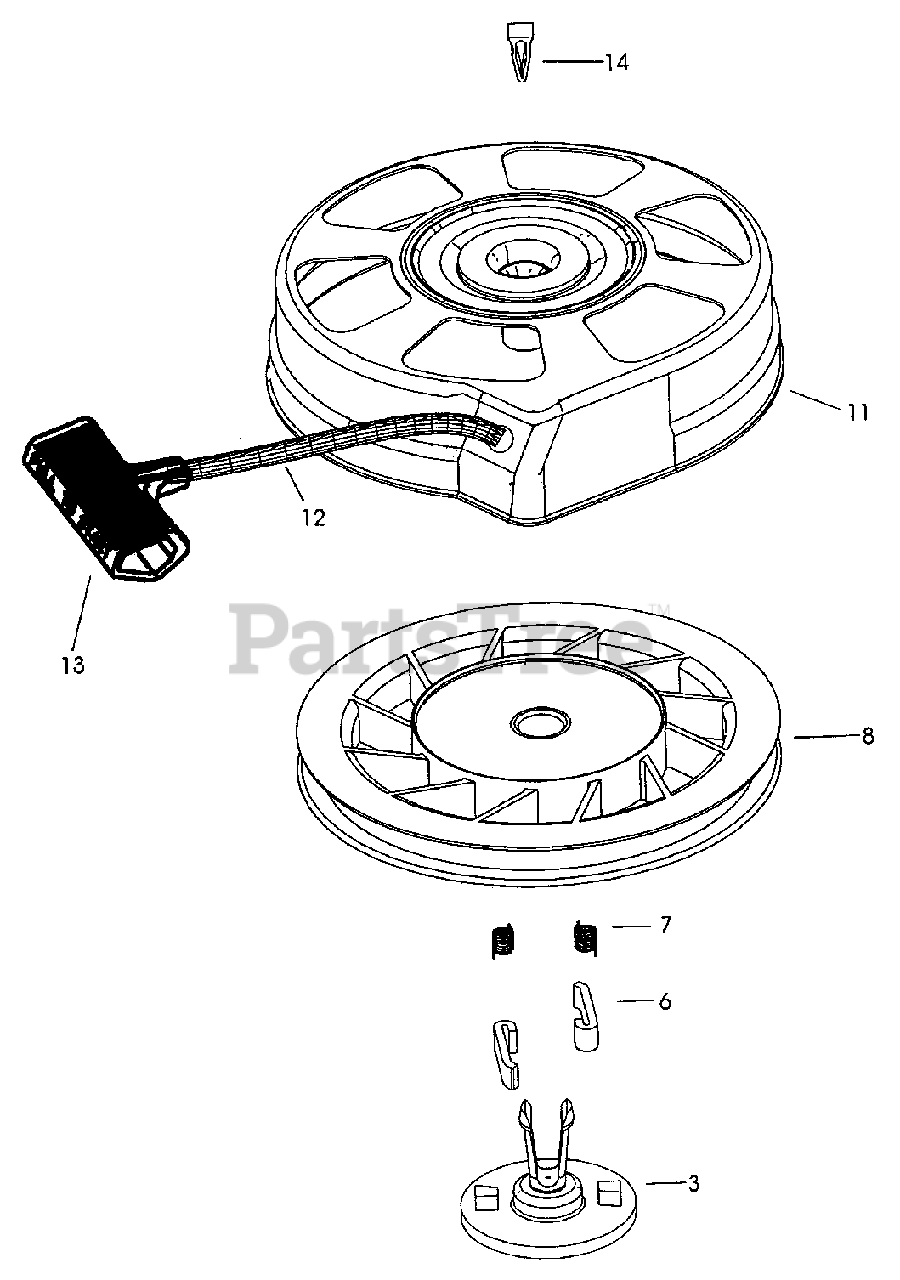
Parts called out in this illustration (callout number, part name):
3	Retainer
6	Starter Dog
7	Dog Spring
8	Pulley & Rewind Spring Ass'y
11	Starter Housing Ass'y (40 degree grommet)
12	Starter Rope (Length 98" x 9/64" dia.)
13	Starter Handle
14	Locking Tab
